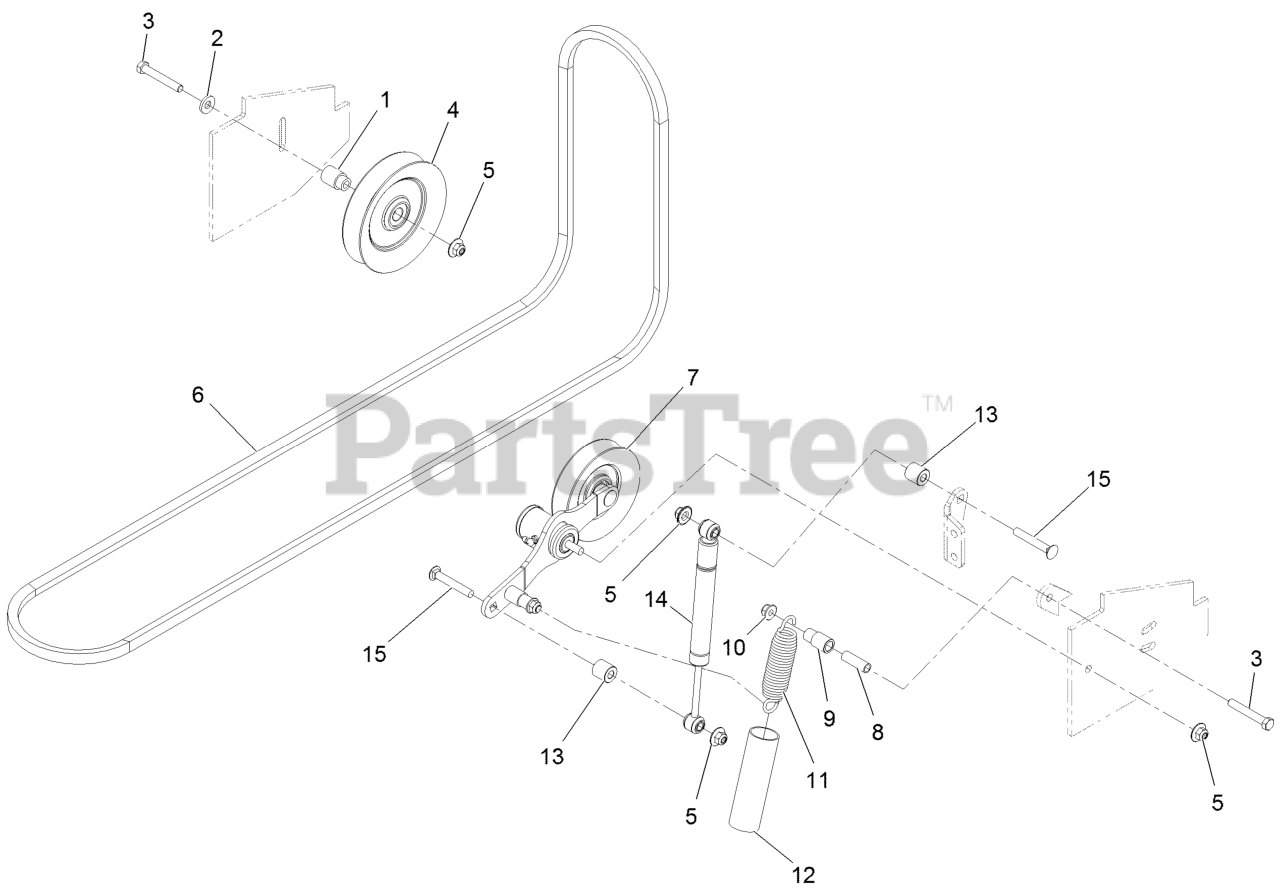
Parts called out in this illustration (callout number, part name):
1	BUSHING-IDLER
2	WASHER-BELLEVILLE
3	BOLT-CARR
4	PULLEY-IDLER
5	Nut-Nyloc 3/8-16 Flg
6	BELT,B 123.2
7	ASM-TTNR ARM W/PULLEY
9	BUSHING,PLASTIC
10	NUT-HF, NI
11	SPRING-EXTENSION
12	DAMPENER,SPRING
13	SPACER-.39IDX.88ODX.88L
14	DAMPER-MULE BELT DRIVE
15	SCREW-CARR
